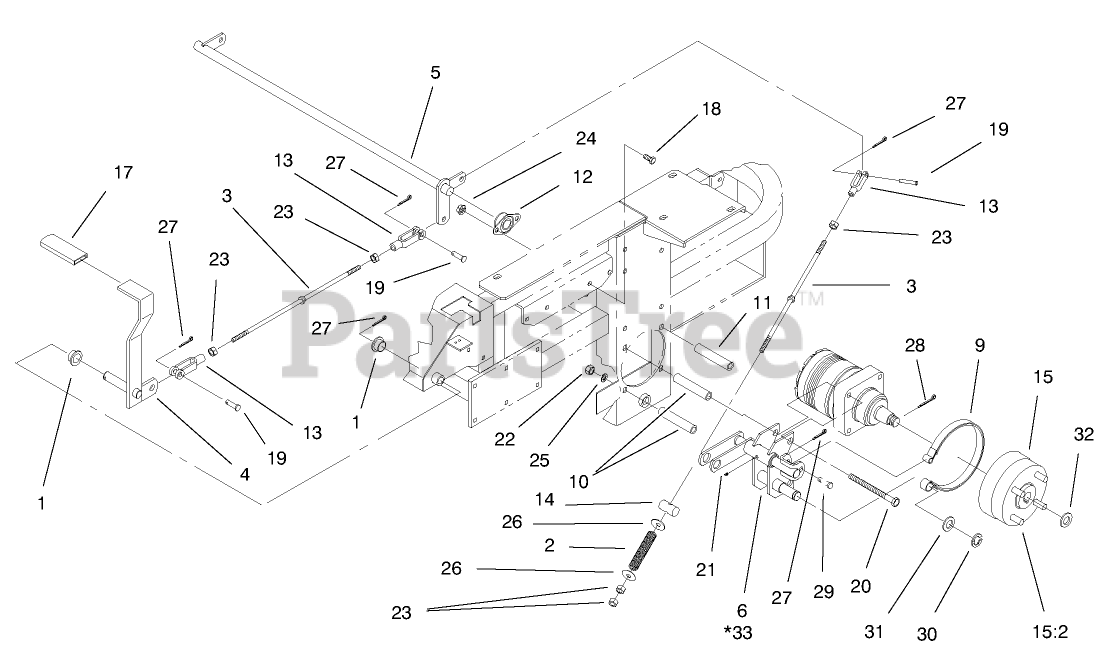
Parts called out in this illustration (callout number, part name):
1	Bearing
2	Spring-Brake
3	Rod-Brake
4	Lever-Brake
5	Shaft-Brake
6	Bracket-Brake LH
9	Band-Brake
10	Spacer
11	Spacer
12	Bearing-Side Flange
13	Yoke-Brake Linkage
14	Pin-Trunion
15	Hub And Drum ASM
15:2	Stud-Wheel
17	Grip-Brake Lever
18	SCREW-HH
19	Pin-Clevis
20	SCREW-HH
21	FITTING-GREASE
22	NUT-HH
23	NUT-HEX
24	NUT-HHF, WHIZ
25	WASHER-LOCK
26	WASHER-FLAT
27	PIN-COTTER
28	Pin-Cotter
29	Pin-Clevis
30	Ring-Retaining
31	WASHER-FLAT
32	Spacer
